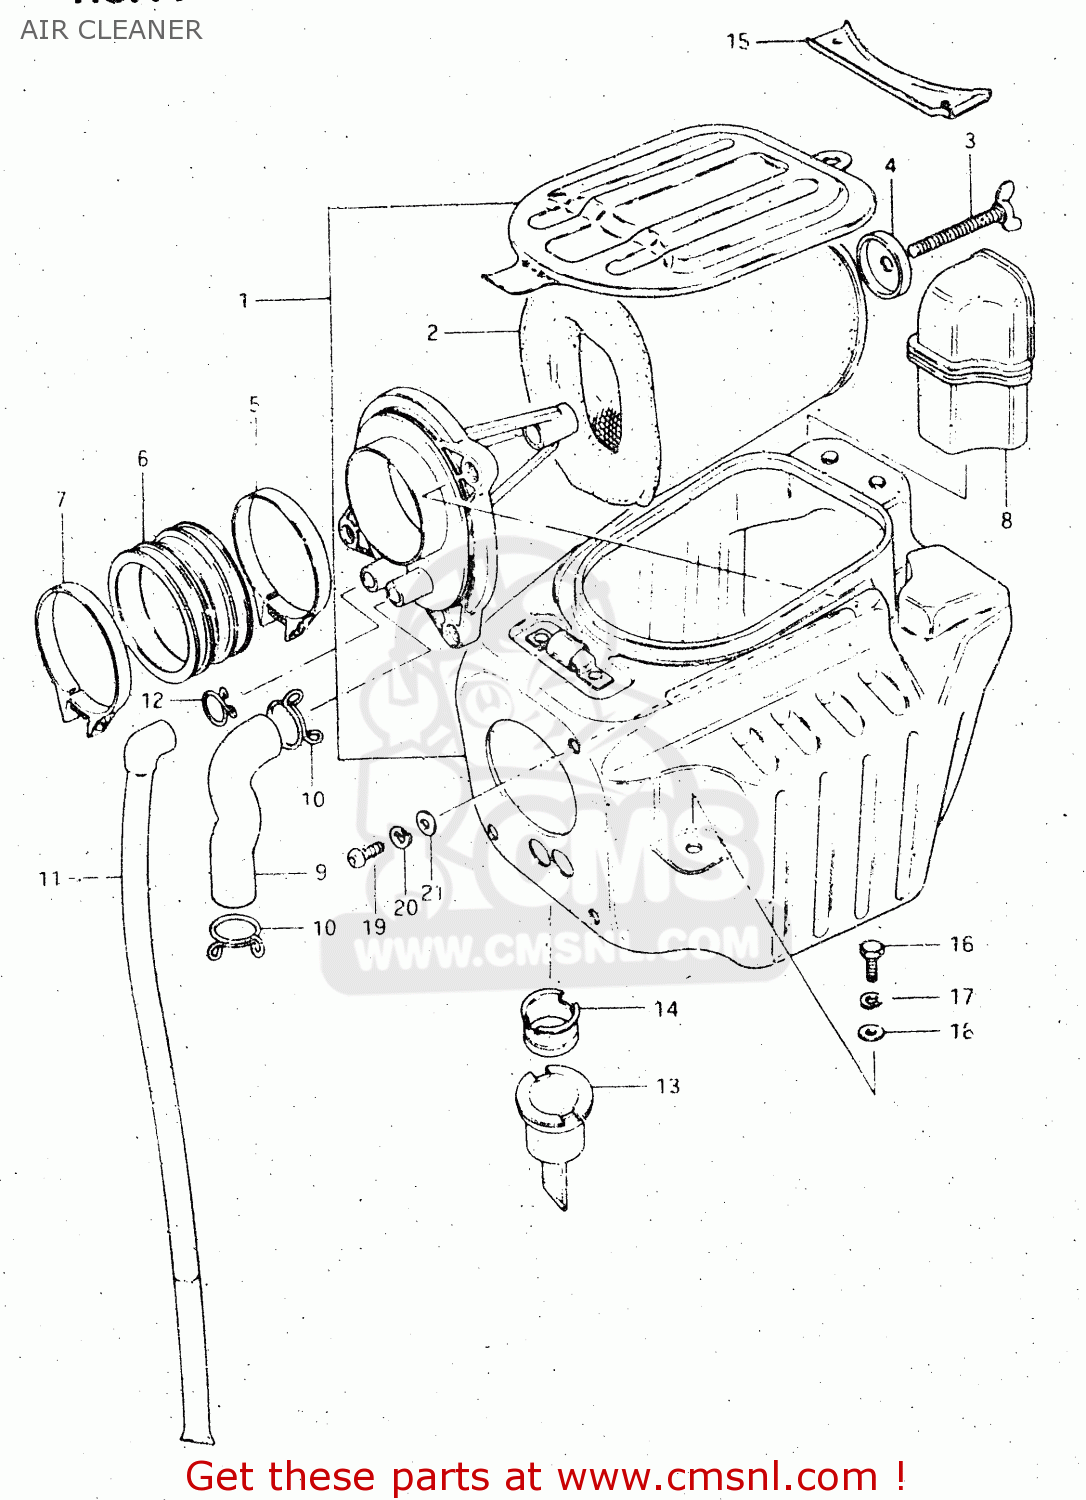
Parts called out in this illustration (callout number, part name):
1	CLEANER ASSY, AIR
2	FILTER
3	WING BOLT,AIR CLEANER
4	HOLDER,FILTER
5	CLAMP
6	TUBE,OUTLET
7	CLAMP
8	TUBE,INLET
9	TUBE,BREATHER
10	CLIP
11	DRAIN TUBE
12	CLIP
13	HOSE,AIR CLEANER DRAIN
14	STOPPER,DRAIN
15	BRACKET,AIR CLEANER
16	BOLT, UPPER
17	LOCK WASHER
18	WASHER
19	SCREW 6X12
20	LOCK WASHER
21	WASHER
